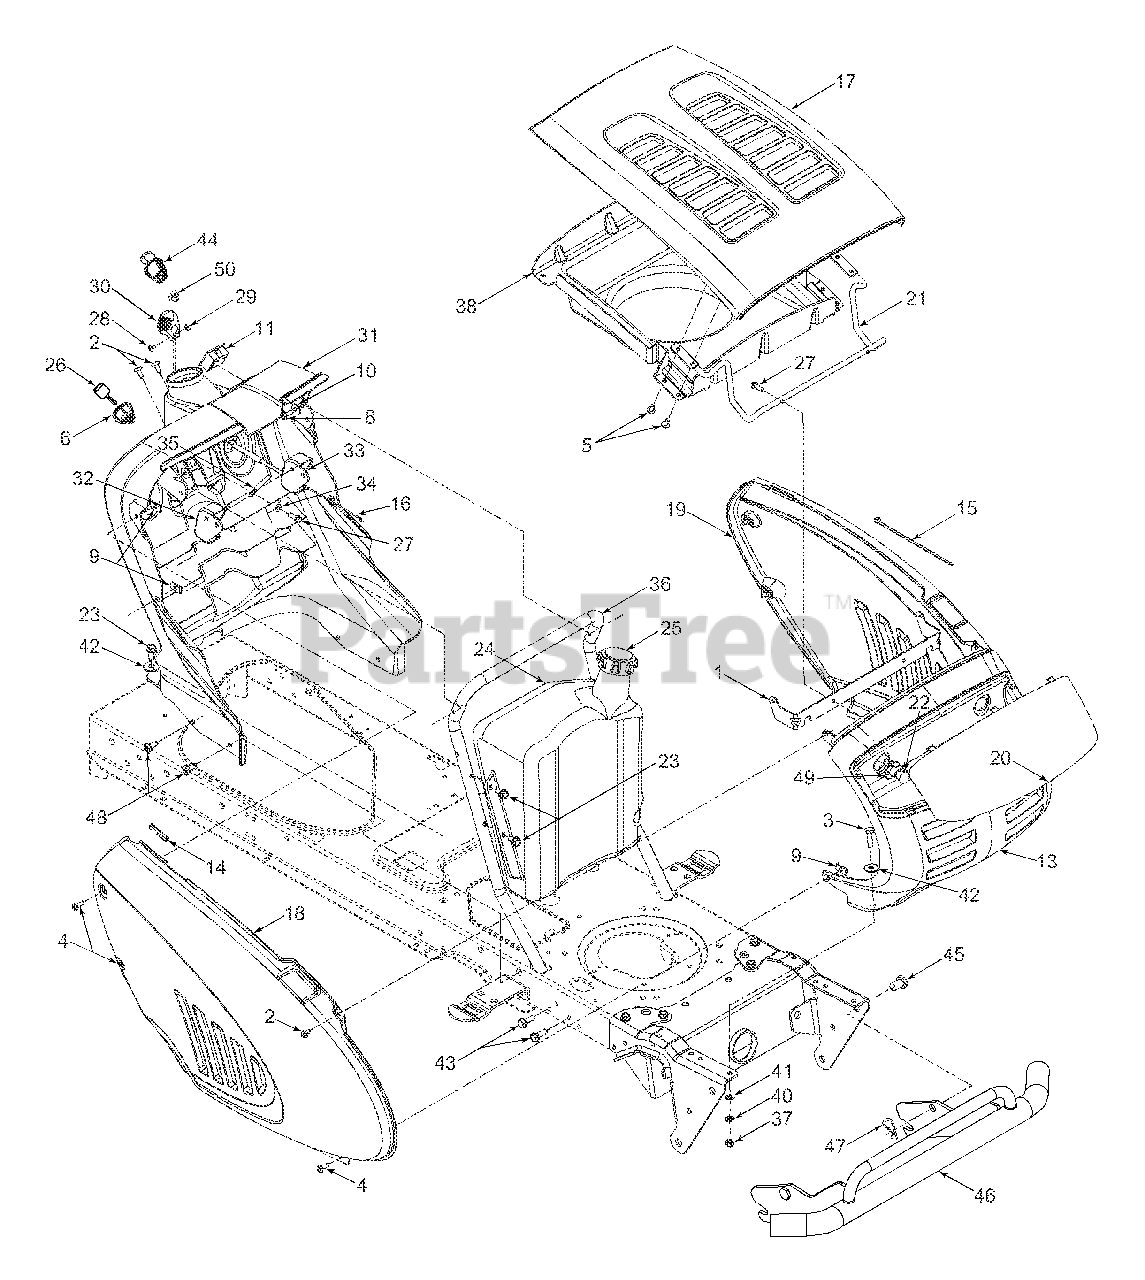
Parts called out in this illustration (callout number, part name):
2	Self-tapping Screw, 1/4-20 x .5
3	Hex Cap Screw, 5/16-18 x 1.25
4	Phillips Pan Screw, 1/4-20 x .75
5	Truss Phillips Screw, 1/4-20 x .625
6	Ignition Switch
8	Self-tapping Screw, 1/4-20 x .75
9	U-type Speed Nut, 1/4-20
10	Bell Washer, .265 x .75 x .062
11	Systems Indicator Monitor w/ Hour Meter
13	Grille (9-style)
14	Trim Strip, 4
15	Cable Tie, 3/16 x .05 x 7.4
16	Choke Knob/Cable (Models with any B&S Twin)
21	Hood Hinge Rod
22	Lamp
23	Self-tapping Screw, 5/16-18 x .625
24	Fuel Tank, Three Gallon
25	Fuel Cap
26	Ignition Key w/ plastic cover
27	Self-tapping Screw, 1/4-15 x .75
28	Truss Phillips Screw, #8-32 x .375
29	Hex Nut, #8-32
30	Throttle Control Knob
31	Dash Panel (Models w/ Electric PTO)
32	Cruise Control Button
33	Parking Brake Button
34	Flat Washer, 9/32 x 1/2 x 1/16
35	Brake/Cruise Pivot Rod
38	Hood Plenum (Models with Kohler)
40	Lock Washer, 5/16
41	Speed Nut, .3125
42	Flat Washer, .349 x 1.0 x .063
43	Screw, 5/16-18 x .88 (Grade 5)
44	Electric PTO Switch
45	Clevis Pin, .50 x .78
46	Bumper Assembly
47	Internal Cotter Pin
48	Screw, 5/16-18 x .75
49	Socket
50	Choke Plug
